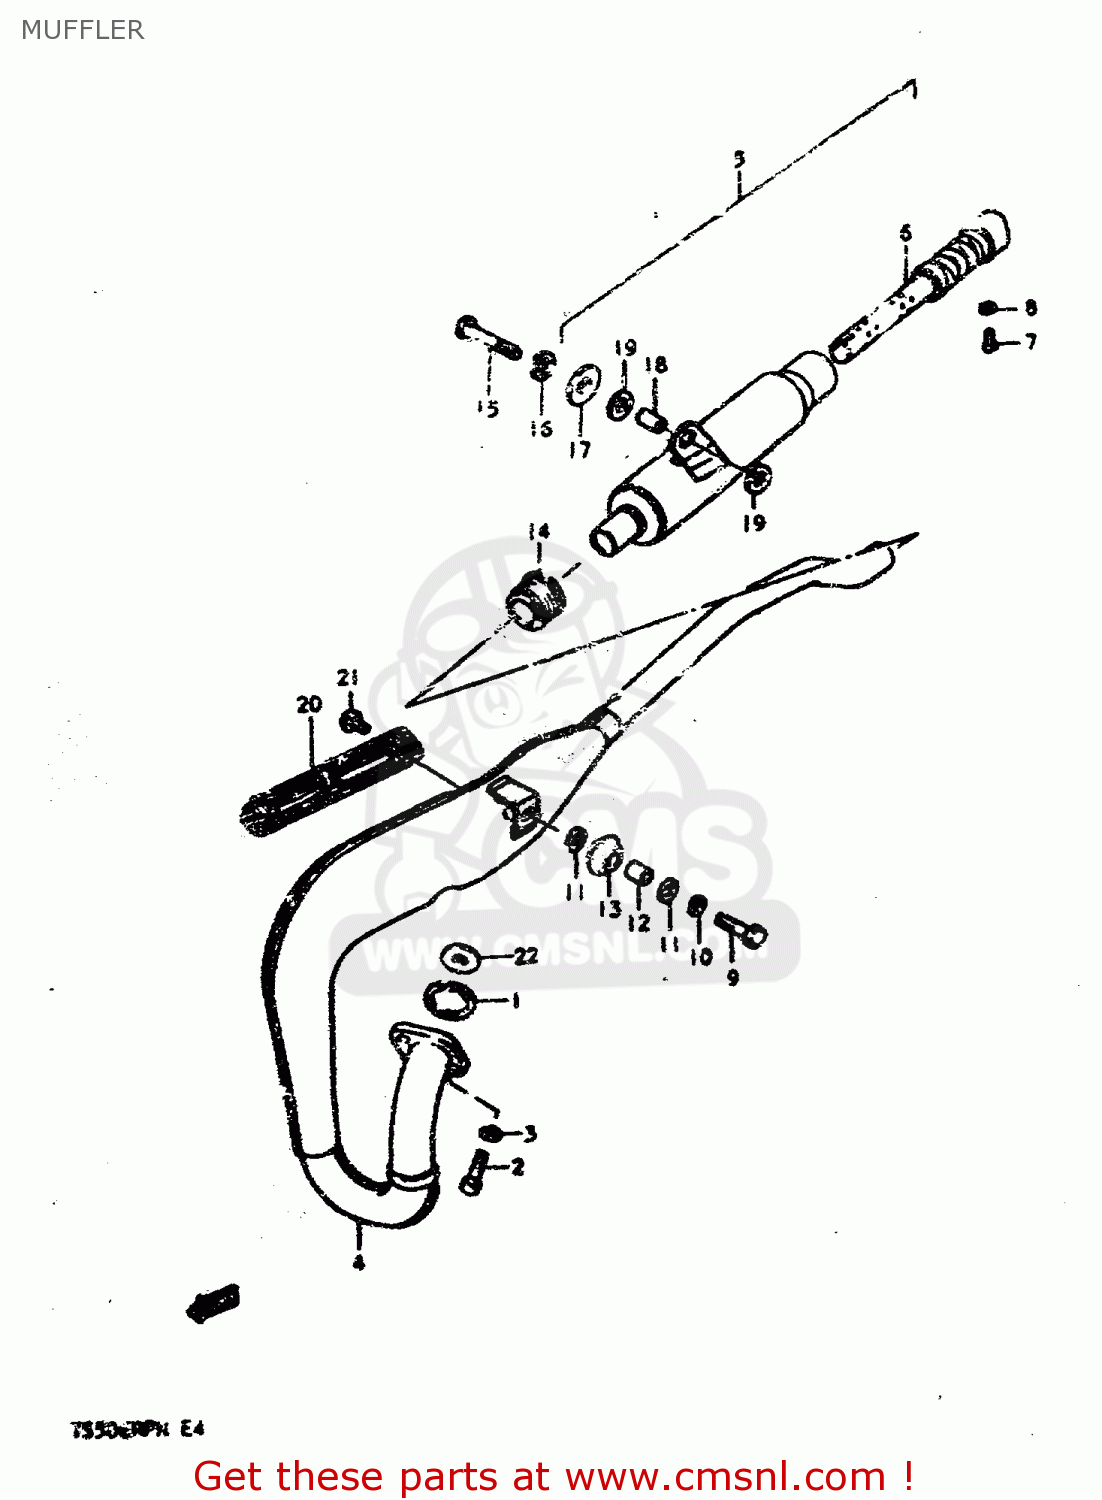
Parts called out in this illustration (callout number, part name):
1	GASKET,EXHAUST PIPE (NAS)
2	BOLT
3	LOCK WASHER
4	MUFFLER, 1ST
5	MUFFLER, 2ND
6	PIPE, BAFFLE
7	BOLT(5X8)
8	LOCK WASHER
9	BOLT (8X30)
10	LOCK WASHER
11	WASHER
12	SPACER (8X12X15)
13	DAMPER,MUFFLER,FR
14	CONNECTOR,MUFFLER
15	BOLT
16	LOCK WASHER
17	WASHER
18	SPACER (8.6X13.8X9)
19	CUSHION
20	COVER, MUFFLER
21	SCREW
22	PLATE, EXHAUST PIPE
